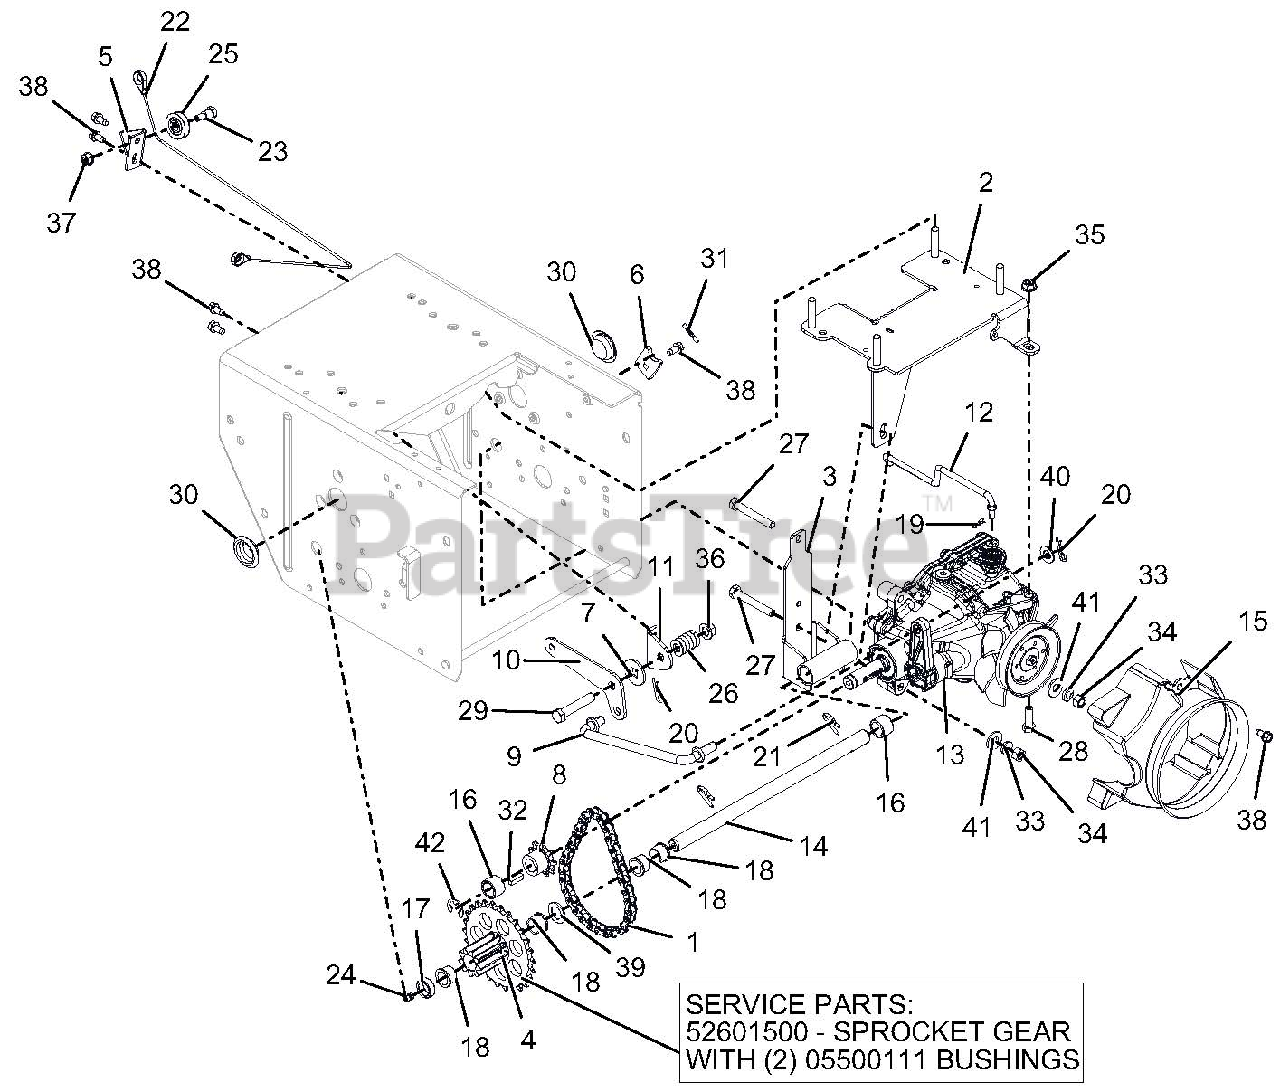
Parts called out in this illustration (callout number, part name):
1	CHAIN - #41, 32 PITCHES
2	BRACKET, HYDROSTATIC TRANS XLG
3	TRANS MOUNT, TENSIONING, WHEEL
4	PINION & SPROCKET
4	PINION & SPROCKET W/BUSHINGS
4	BSHG-FLG .625X.750X.500X.875
5	BRACKET, CABLE PULLEY
6	TAB, ANTI ROTATION
7	FRICTION WASHER
8	SPROCKET, PINION 9T W/KEY
9	ROD, HYDRO TRANS SHIFT
10	PIVOT, HYDRO TRANS SHIFT
11	BRACKET, HYDRO SHIFT PIVOT
12	ROD, HYDRO BYPASS
13	TRANSMISSION, HYDROSTATIC
14	SHAFT, PINION - HARDENED
15	SHROUD, HYDROGEAR RT-310
16	SPACER, .635X.880X.611
17	BSHG-SLV, .635X.880X.305
18	BSHG-FLG .625X.750X.500X.875
19	PIN-HAIR INT .06X.18X.77
20	PIN-HAIR INT .08X.18X1.18 YWZC
21	PIN, SPRING CLIP
22	CABLE, TRACTION, HYDRO PRO
23	BOLT, SHLDR-.375X.375X.25-20
24	ZERK,FITTING .25X.125 DRIVE IN
25	PULLEY, CABLE
26	SG-COMP .187X.56X1.62
27	@BLT-HEX .31-18X2.25 GR5 YWZC
28	@BLT-HEX .31-18X1.00 GR5 YWZC
29	@BLT-HEX .38-16X2.00 GR5 YWZC
30	PLUG, HOLE - 1.125"
31	@PIN-GRV .125X1.00 TP E ALLOY
32	KEY-SQ .188X.75X.188
33	WSHR-LK .312X.097 HVY YWZC
34	@NUT-HEX .31-18 YWZC
35	@NUT-LK-TOP-FLG .31-18 YWZC
36	@NUT-LK-TOP-FLG .38-16 YWZC
37	@NUT-LK-TOP-FLG .25-20 YWZC
38	SCR-TAP .25-20X.50 HWH TR YWZ
39	WSHR-FL-STL .630X1.005X.062 YZ
40	@WSHR-FL-STL.406X.812X.065 YWZ
41	@WSHR-FL-STL.38X.875X.083 YWZC
42	RG-RTNG-EXT .625X.042
